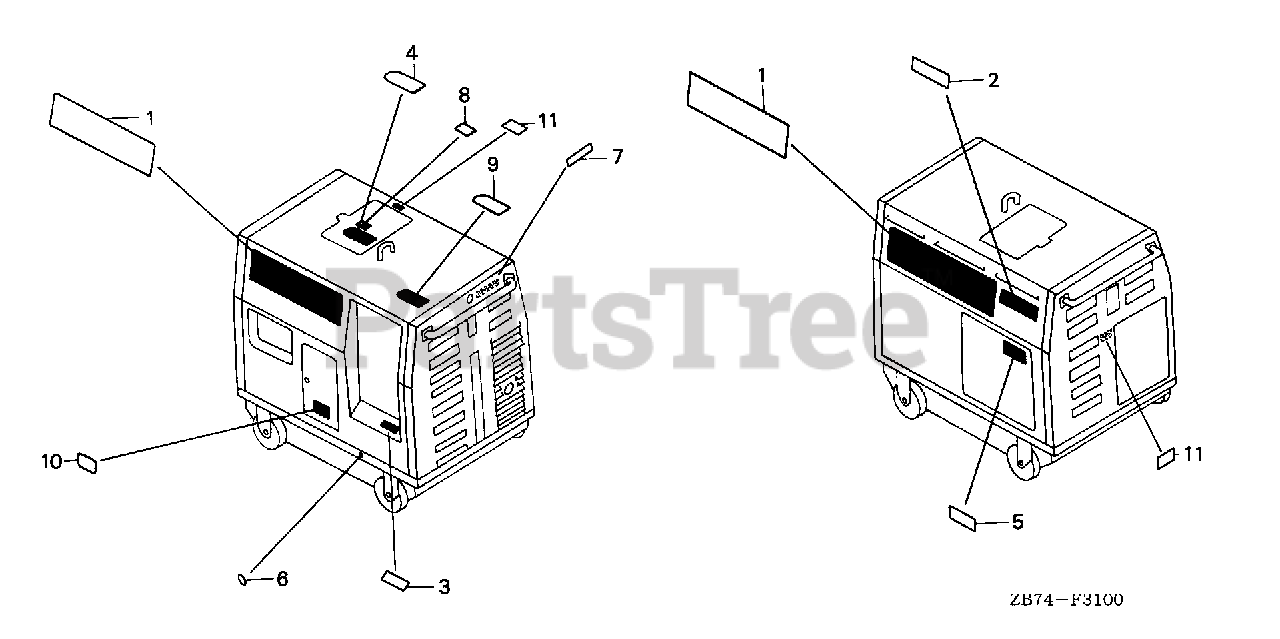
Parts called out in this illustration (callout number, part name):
1	EMBLEM (EX3300)
2	PLATE, CAUTION
3	LABEL, RAIN WARNING (ENGLISH)
4	MARK, CAUTION (ENGLISH/FRENCH)(SPANISH)
5	MARK, AIR CLEANER
6	MARK, GROUND
7	MARK, EX. CAUTION
8	MARK, CAUTION (CO)(ENGLISH/FRENCH)(SPANISH)
9	LABEL, CONNECT WARNING (ENGLISH)
10	MARK, OIL CAUTION
11	LABEL, FUEL CAUTION
